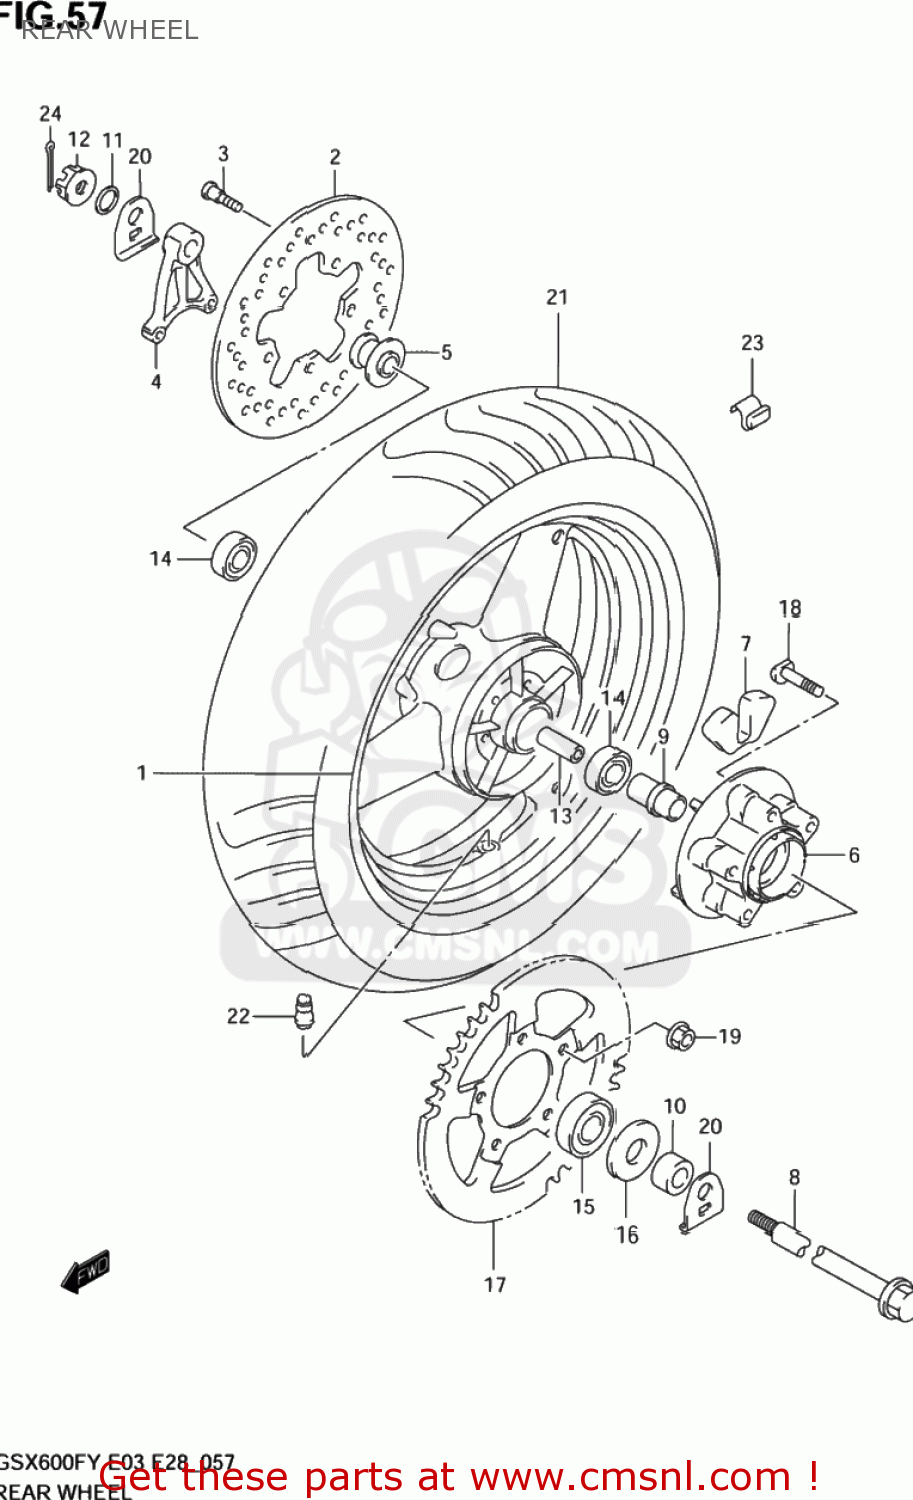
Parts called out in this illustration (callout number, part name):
1	WHEEL,REAR,17X
2	DISC,RR BRAKE
3	BOLT 8X33
4	BRACKET,RR CALIPER
5	SPACER,RR AXLE,R
6	DRUM,RR SPROCKET
7	ABSORBER,RR HUB SHOCK
8	AXLE,RR
9	RETAINER,RR SPROCKET DRUM
10	SPACER,RR AXLE,R
11	WASHER(17X30X3.2)
12	NUT
13	SPACER(17.5X25X88)
14	BEARING
15	BEARING(25X62X17)
16	SEAL,OIL(35X62X8)
17	SPROCKET,RR(NT:47-530)
18	BOLT(10X47)
19	NUT
20	WASHER,CHAIN ADJUSTER
21	TIRE 150/70 ZR17 (69W) M
22	VALVE ASSEMBLY,WHEEL,TR412
23	BALANCER,WHEEL (10G)
24	PIN,COTTER
